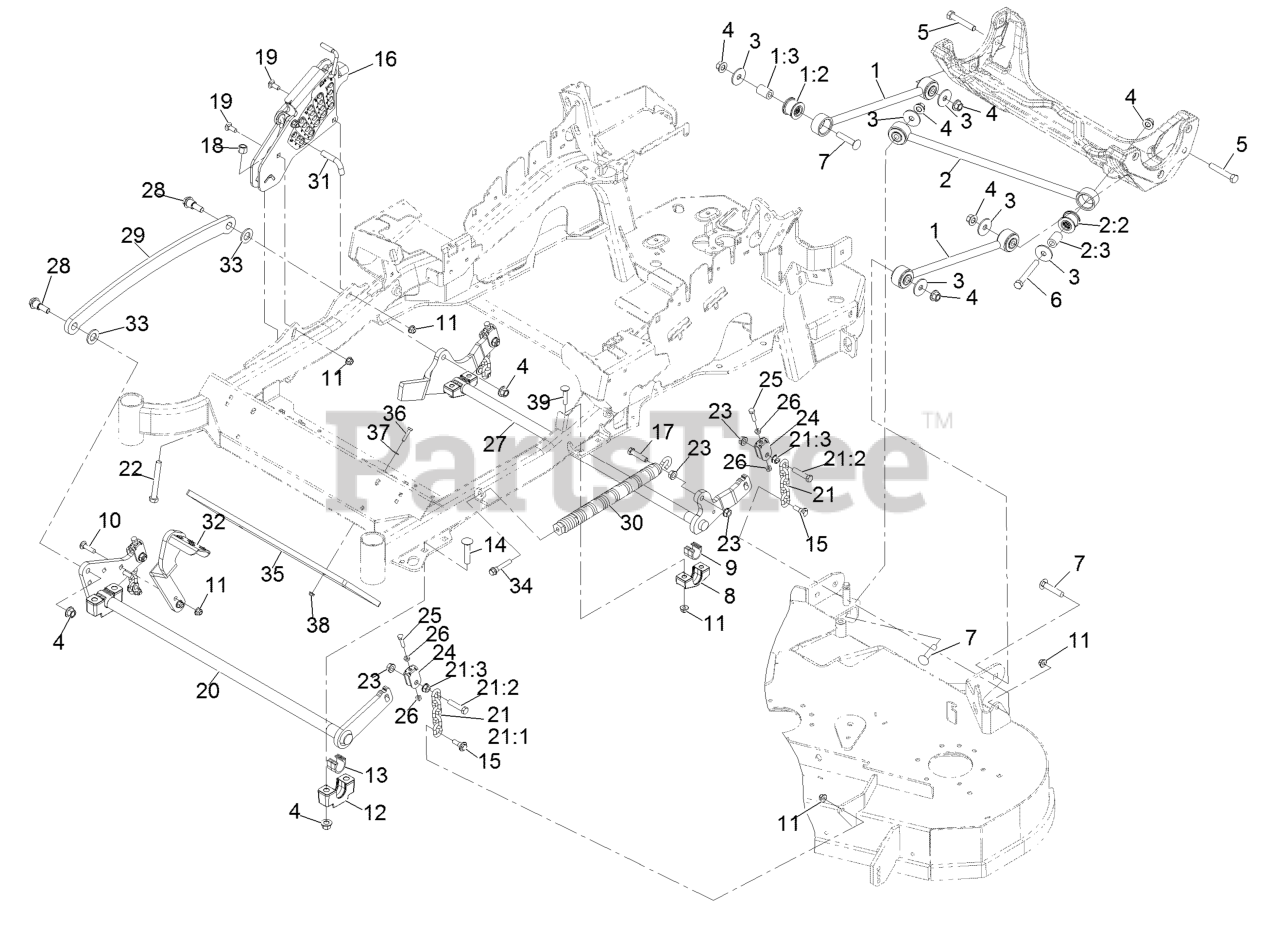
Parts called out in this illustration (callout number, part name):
1	DECK STRUT ASM
1:2	BUSHING-SUSPENSION, RUBBER
2	PANHARD ROD ASM
2:2	BUSHING-SUSPENSION, RUBBER
3	WASHER-THRUST
4	Nut-Lock 1/2-13
5	SCREW-HH
6	SCREW-HH
7	SCREW-CARR
9	BEARING-CROSS SHAFT, REAR
10	SCREW-CARR
11	NUT-HF, NI
12	SUPPORT-CROSS SHAFT, BEARING
13	BEARING-CROSS SHAFT, FRON
14	Bolt-Carriage 1/2-13 X 2 1/2 Spl Neck
15	SCREW-SHOULDER, HHF
16	HOC ASM
17	SCREW-HH
18	NUT-LOCK, NI
19	BOLT-CARR
20	DECKLIFT-FRONT
21	DECK LIFT CHAIN ASM
21:1	CHAIN-LIFT, DECK
21:2	SCREW-HH
22	BOLT-TAP
24	YOKE-ADJUST, DECK
25	SCREW-HH
26	NUT-JAM
27	LIFT-DECK, REAR
28	SCREW-SHOULDER, HHF 1/2-13 X 1.12
29	LINK-LIFT, DECK
30	SPRING-EXTENSION
31	PIN-HOC
32	LEVER-FOOT
33	WASHER-FLAT
34	BOLT-SHOULDER
35	WEIGHT,TOE BOARD
36	SCREW-HH
37	WASHER-FLAT
39	SCREW-CARR
